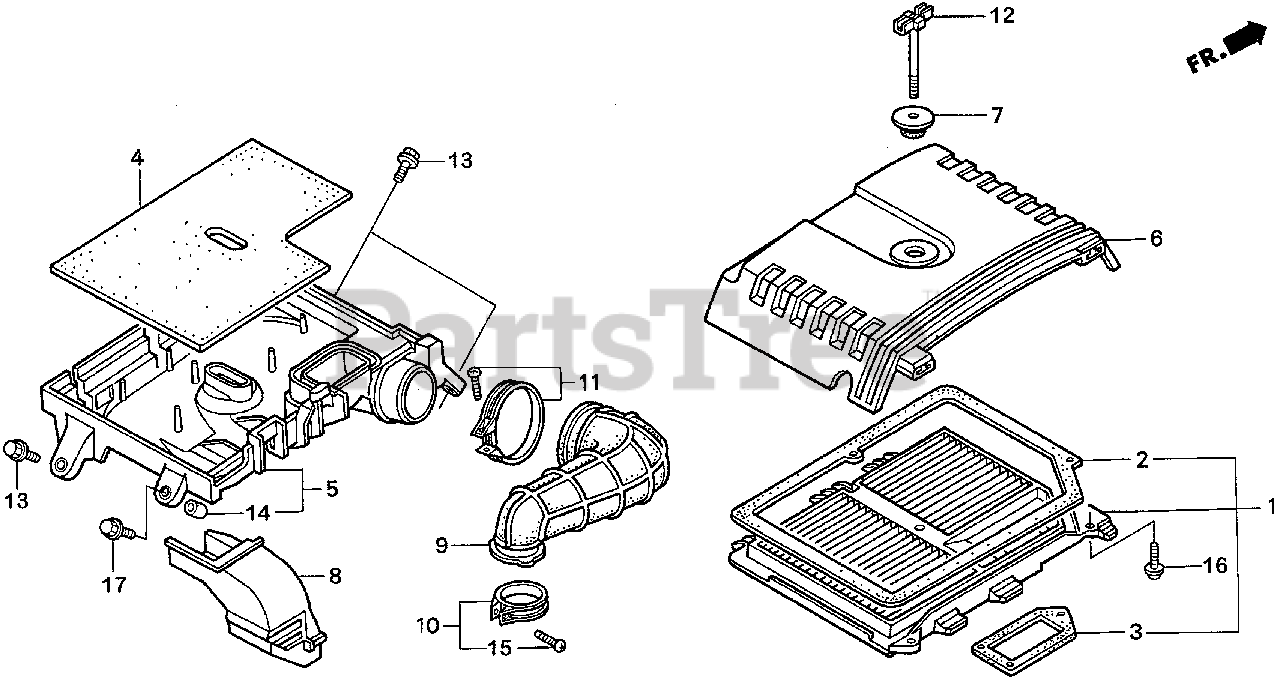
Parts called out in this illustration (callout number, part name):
1	ELEMENT SET, AIR CLEANER
2	GASKET A, ELEMENT
3	GASKET B, ELEMENT
4	FILTER (OUTER)
5	HOUSING, AIR CLEANER
6	COVER, AIR CLEANER
7	GROMMET, AIR CLEANER
8	HOSE, AIR CLEANER (NOT AVAILABLE)
9	TUBE, AIR CLEANER CONNECTING
10	BAND, A/CLNR TUBE
11	BAND, AIR CLEANER CONNECTING TUBE (50)
12	BOLT, AIR CLEANER
13	BOLT, FLANGE (6X23)
14	COLLAR, AIR CLEANER HOUSING
15	SCREW, PAN (4X20)
16	SCREW-WASHER (5X16)
17	BOLT, FLANGE (6X18)
